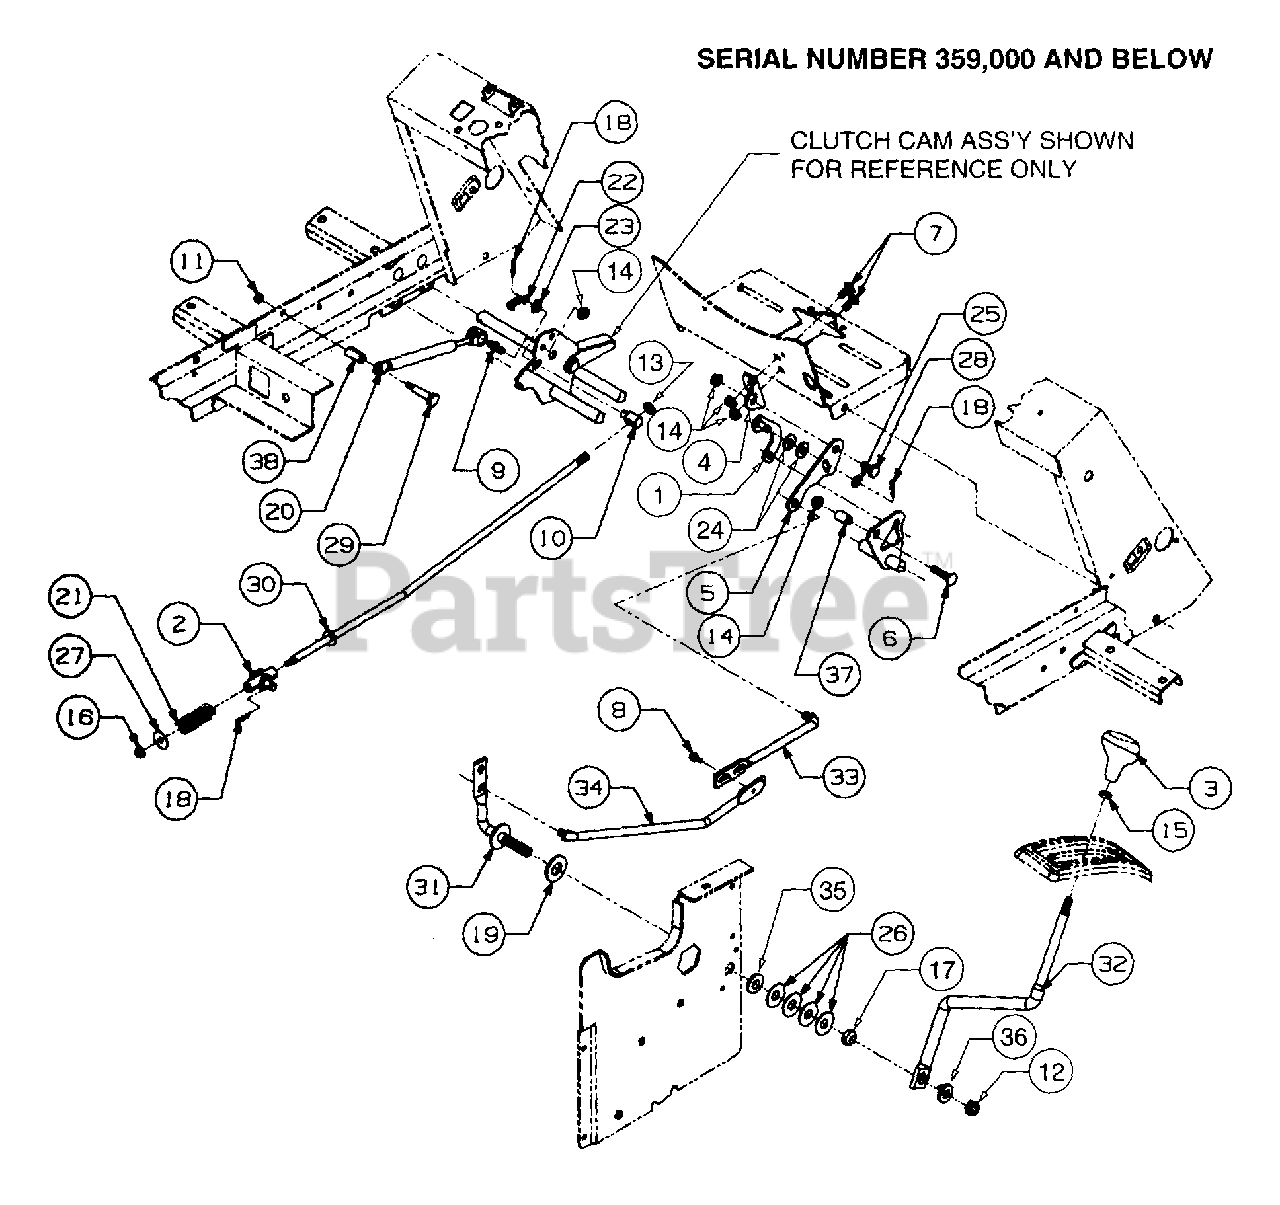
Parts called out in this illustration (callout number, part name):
1	Bracket, Cruise Return
2	Pivot Assy, Sleeve
3	Knob, Shifter
6	Bolt, Carriage, 5/16-18 x 1.5
7	Bolt, Carriage, 5/16-18 x .75
8	Screw, Hex Wash Hd Tapp 1/4-20 x .50
9	Screw, Ball, 5/16-18
10	Ferrule, Adjustment
11	Nut, Hex Sems, 1/4-20
12	Nut, Hex Top Lock, 1/2-20
13	Nut, Hex Jam, 3/8-24 GR5
14	Nut, Hex Flange Lock, 5/16-18
15	Nut, Hex Jam, 3/8-16 GR5
16	Nut, Hex Flange Lock, 1/4-20
17	Nut, Hex, 1/2-20
18	Pin, Internal Cotter
19	Washer, Friction
20	Cylinder, Damper
21	Spring, Compression, .63 ID x 2.0
22	Spring, Extension, .38 OD x 1.44
23	Washer, Flat, .406 x .75 x .063
24	Washer, Flat, .375 x .870 x .090
25	Washer, Flat, 5/16
26	Washer, Bell
27	Washer, Flat, .265 x 1.0 x .03 Hdn
28	Bolt, Shoulder, .437 Dia x .180 Lg
29	Bolt, Shoulder, .347 Dia x 1.375
30	Rod, Hydro Adjustment
31	Rod, Shift
32	Rod, Gear Selector
33	Link, Front Hydro Shifter
34	Link, Rear Hydro Shifter
35	Bushing, Shoulder
36	Hub, Shift
37	Spacer, .377 ID x .50 OD x .830
38	Spacer, Tubing, .375 x .52 x 1.04
